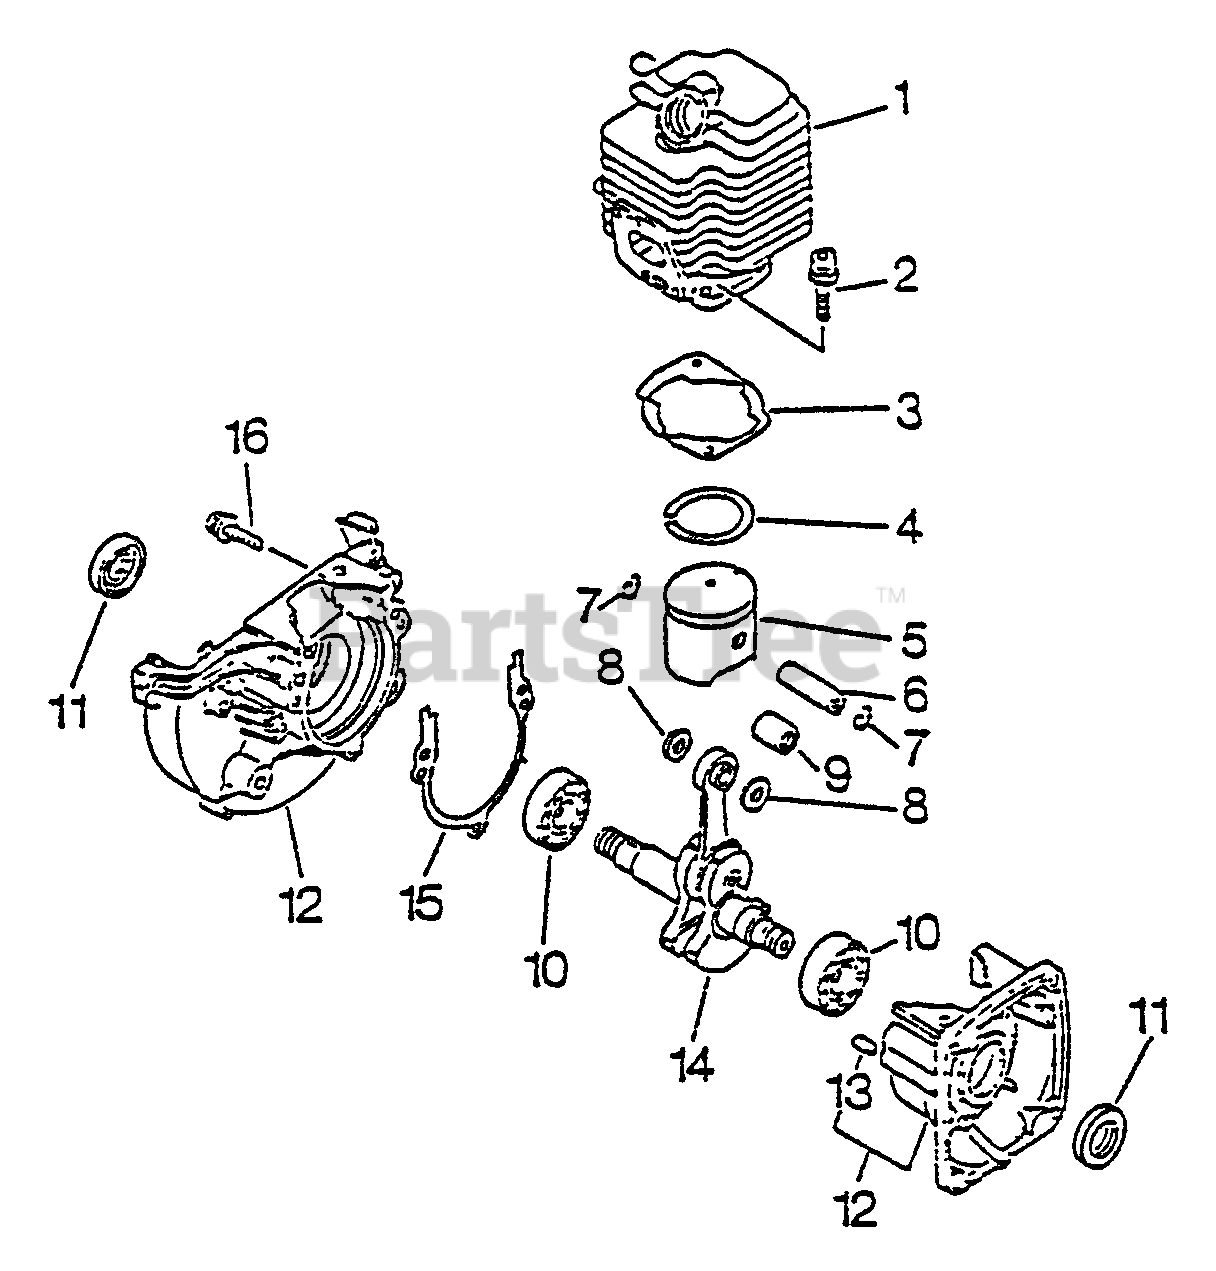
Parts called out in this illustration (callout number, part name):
1	CYLINDER
2	SCREW - 5X22
3	GASKET, CYLINDER
4	RING, PISTON
5	PISTON
6	PIN, PISTON
7	RING, RETAINING
8	SPACER, PISTON
9	BEARING, NEEDLE
10	BEARING, BALL - 6201
11	SEAL, OIL
12	CRANKCASE KIT
13	PIN - LOCATING
14	CRANKSHAFT ASSY
15	GASKET, CRANKCASE
16	SCREW - 5X28
